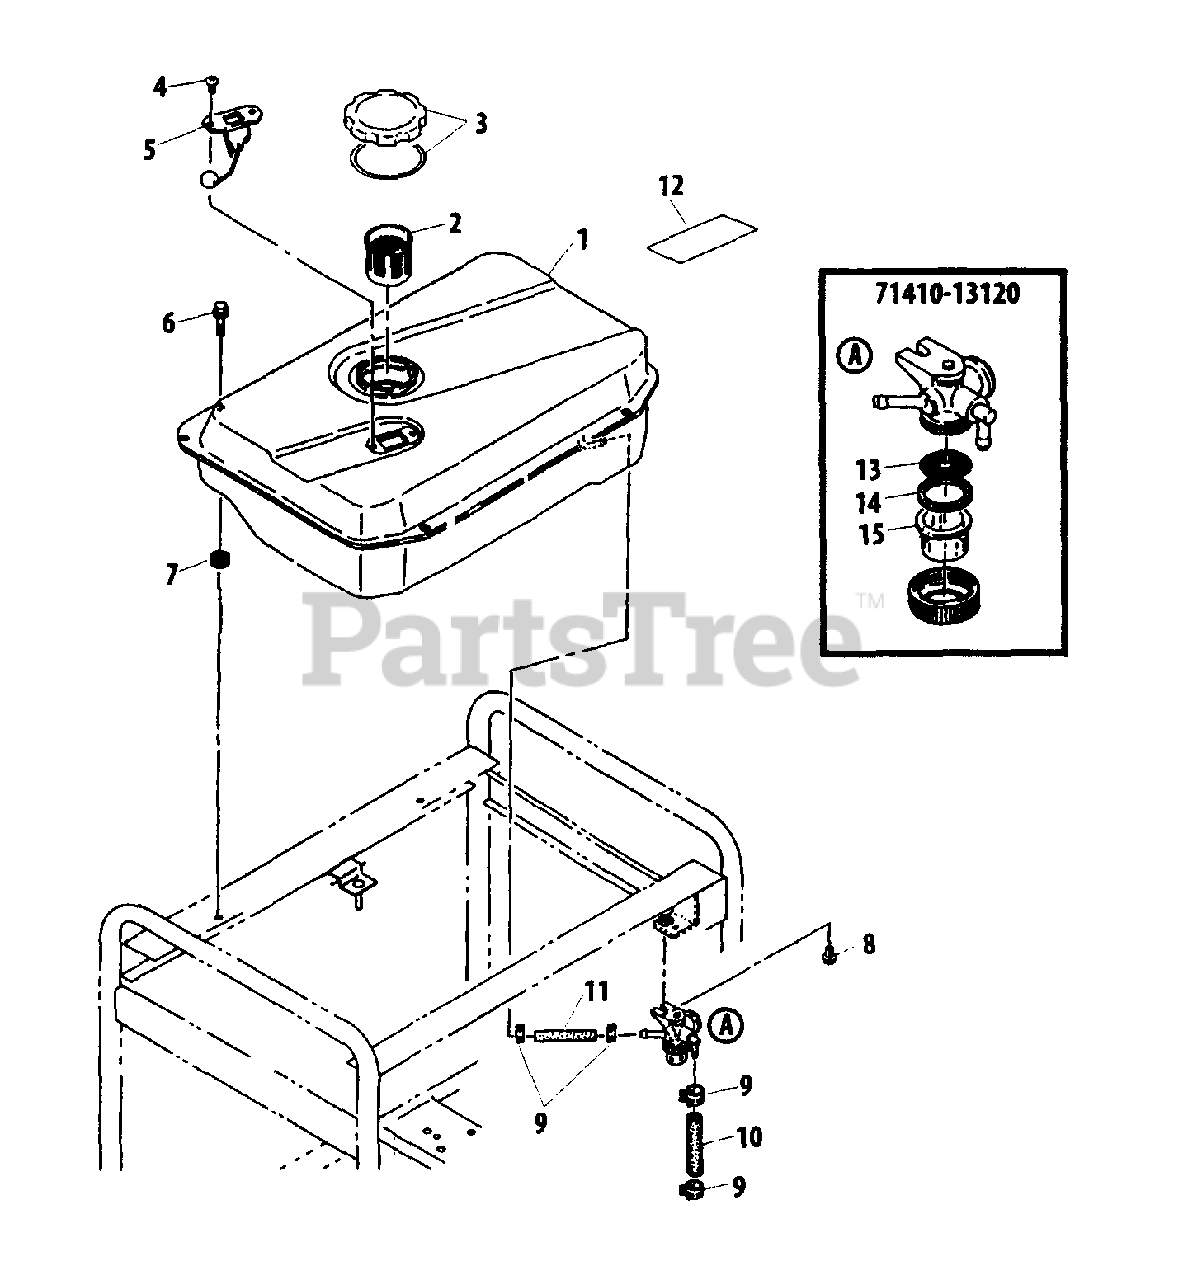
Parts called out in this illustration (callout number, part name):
1	TANK, FUEL
2	STRAINER, FUEL
5	GAUGE, FUEL
8	BOLT - 6X16
9	CLAMP, HOSE
10	PIPE - 6X12X210
11	FUEL - 6X12X80
12	LABEL - CAUTION
71410-13120	FUEL VALVE ASSY
